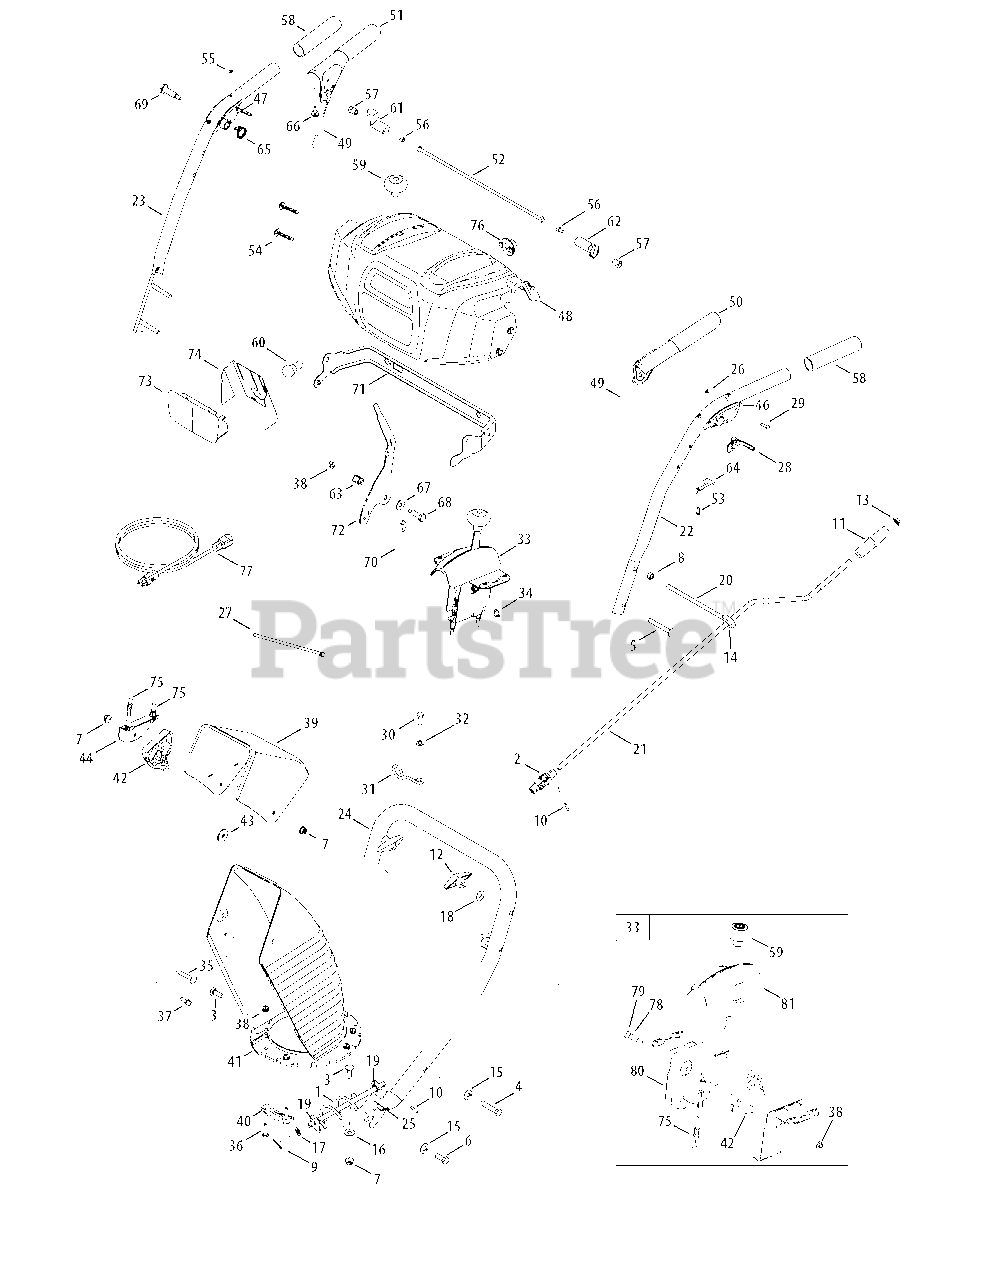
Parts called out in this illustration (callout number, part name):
1	Chute Crank Assembly
2	Joint Block Assembly
3	Screw, Carriage, 5/16-18 x 1.0
4	Screw, Hex, 3/8-16 x 2.00 Lock, Gr5
5	Screw, Carriage, 5/16-18 x 2.5
6	Screw, Hex, 3/8-16 x 1.0 Lock, Gr5
7	Flange Lock Nut, 5/16-18
8	Hex Nut, 5/16-18
9	Internal Cotter Pin
10	Spring Pin
11	Knob, Crank
12	Knob, Wing Nut, 5/16-18
13	Cap, Push, 3/8
14	Grommet, Rubber
15	Washer, Bel, .375 x .87 x .063
16	Washer, Flat, .349 x .879 .063
17	Washer, .375 x .738 x .063
18	Washer, Belleville, .34 x .872 x .06
19	Plastic Bushing, .380 I.D.
22	Handle, Upper - LH
23	Handle, Upper - RH
24	Handle, Lower
25	Chute Crank Bracket
26	Ring, Retainer
27	Cable Tie
30	Hex Head Screw, MB 1.25
31	Cable Guide
32	Flat Washer, .330 x .630 x .0635
33	2-Way Chute Control™ Assy
34	Hi-Lo Screw, 1/4-15 x 0.5
35	Bolt, Carriage, 5/16-18 x 1.75
36	Screw, 1/4-20 x 1.00
37	Hi-Lo Screw, 1/4-15 x .75
38	Flange Lock Nut, 1/4-20
39	Upper Chute
40	Chute, Flange Keeper
41	Lower Chute
42	Chute Tilt Cable Guide
43	Flat Washer
44	Cable Bracket
46	Handle Clutch Lock - LH
47	Handle Clutch Lock - RH
48	Handle Panel
49	Cable Assembly, Auger/Drive
50	Handle Engage Assy - LH
51	Handle Engage Assy - RH
52	Rod Ass’y, Clutch Lock Pivot
53	Screw, #8-16 x 0.50
54	Screw, 1/4-20 x 1.625
55	Screw, #10-24 x 0.375
56	Screw, 1/4-20 x.375
57	Shoulder Nut, 1/4-20
58	Hand Grip
59	Shift Knob
62	Clutch Lock Cam
63	Compression Spring
64	Clutch Lock Spring
65	Torsion Spring
66	Rubber Bumper
67	Flat Washer, .385 x .87 x .06
68	Shoulder Screw
69	Shoulder Screw, 1/4-20 x 1.345
70	Speed Selector Cable
71	Panel Bracket
73	Lens Panel
74	Reflector Label
75	Cable, Chute Tilt
76	Light Socket
77	Extension Cord, 110V
78	Washer, Spring, .39 x .625 x .012
79	Screw, Shoulder, .31 x .995:1/4-20
80	Bracket, Mounting
81	Cover, Tilt Cover
